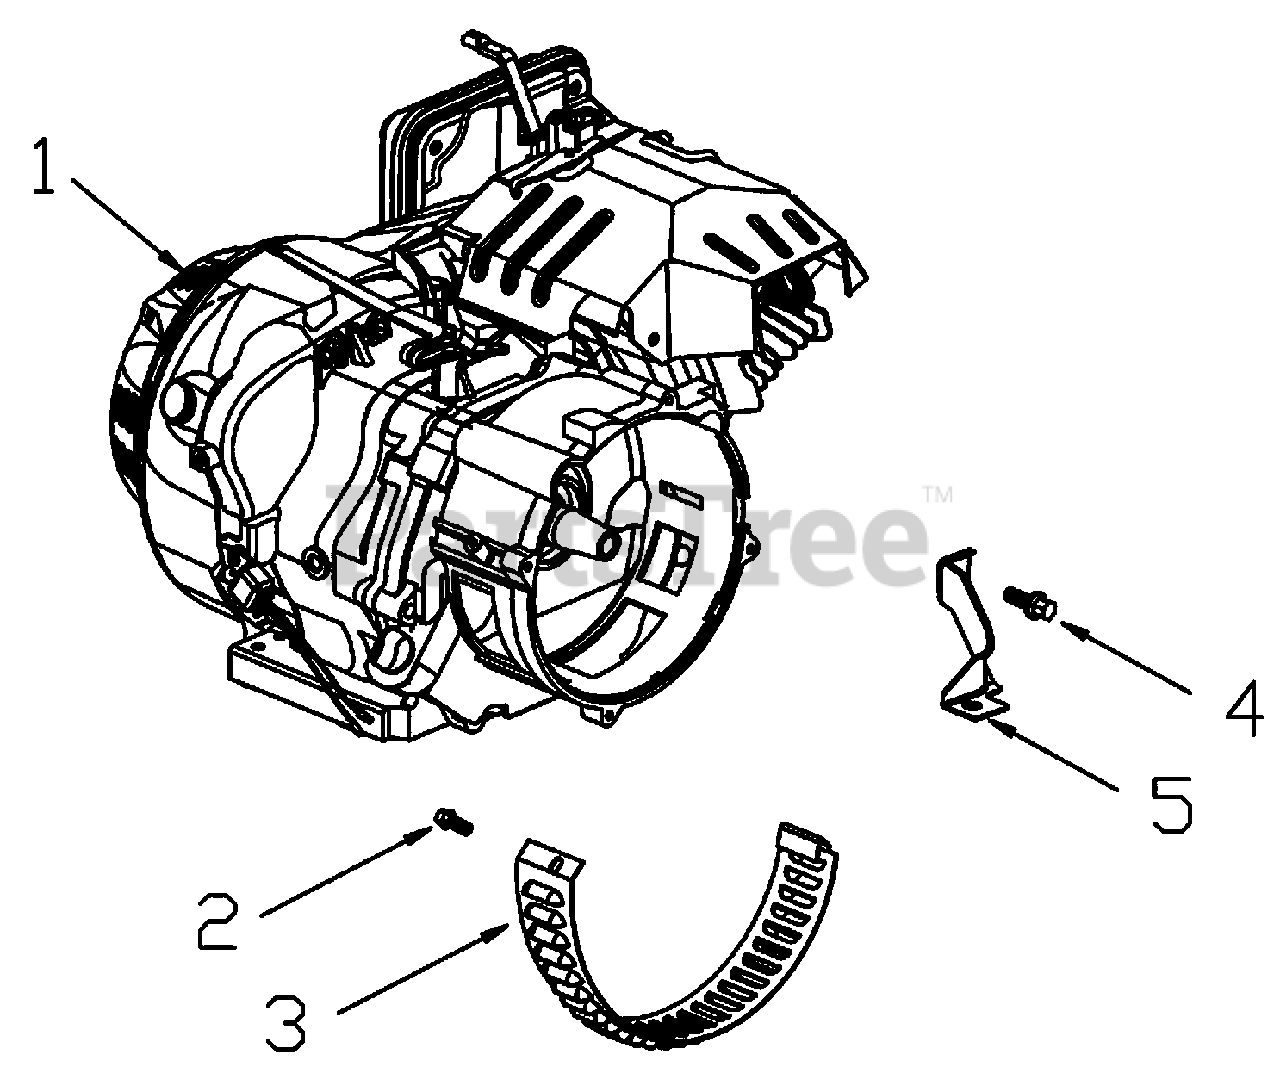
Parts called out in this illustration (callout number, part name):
1	ENGINE G420FDA
2	BOLT, FLANGE M5x10
3	ALTERNATOR SCROLL
4	BOLT, FLANGE M6x12
5	BRACKET, AIR CLEANER
